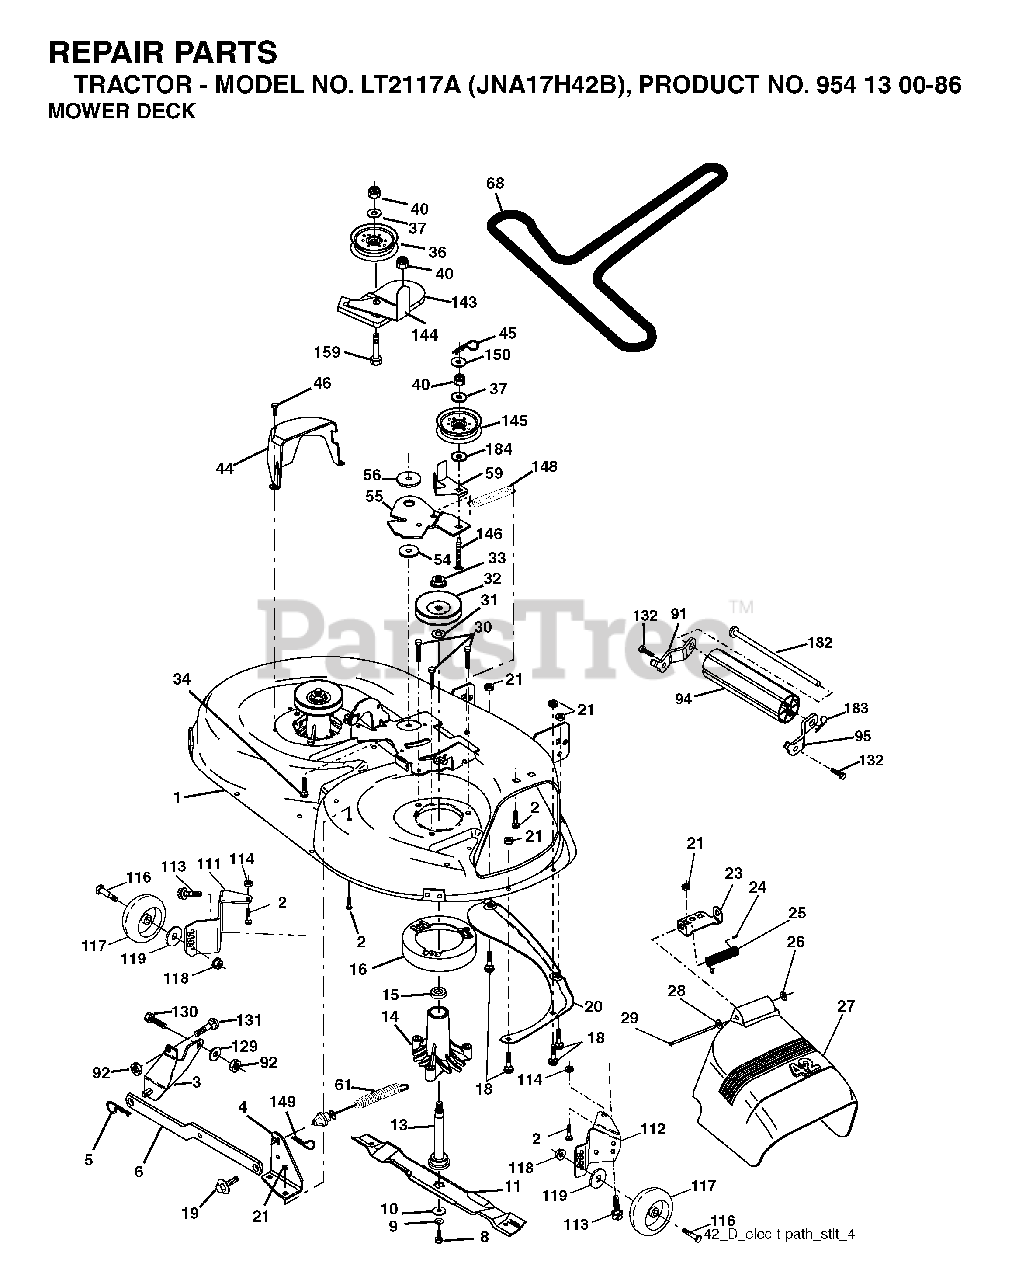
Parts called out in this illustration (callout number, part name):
1	42" DECK KIT
2	BOLT
3	BRKT ASM SWAY BAR
4	BRACKET SWAY BAR 42" DECK
5	RETAINER-SPRNG RB
6	BAR SWAY DECK
8	BLADE BOLT
9	LOCKWASHER
10	WASHER.BLADE
11	BLADE.42".MULCH
13	SHAFT ASM VENT
14	HSG MANDREL
16	STRIPPER, MWR ROUND
18	BOLT
19	BOLT SHD 5/16-18
20	BAFFLE.VORTEX
21	LOCKNUT
23	BRKT, DEFL. MOWER
24	CAP-SLEEVE LT
25	SPRING TORSION
26	NUT PUSH M
27	SHIELD DEFLECTOR
28	WASHER
29	ROD.HINGE
30	SCREW, WASHER HEAD
31	WASHER
32	PULLEY/MANDREL
33	NUT, FLG TOPLOCK 9/16"
34	BOLT
36	FLAT IDLER PULLEY
40	LOCKNUT
44	GUARD MANDREL LH BLACK
45	RETAINER M
46	SCREW.1/4-20X5/8
55	ARM IDLER 42" MOWER LT/YT
56	SPACER.RETAINER.MOWER
59	GUARD, BELT
61	SPRING EXT ELEC CLUTCH
68	V-BELT PRIMARY 42"
91	BRACKET ASM NOSEROLLER LH
92	NUT
94	NOSE ROLLER
95	BRACKET ASM NOSEROLLER RH
111	BRACKET, WHEEL
112	BRACKET, WHEEL
113	SCREW.3/8-16X.625
114	NUT
116	PEDAL COVER T
117	WHEEL.GAUGE.STANDARD
118	LOCKNUT
119	WASHER
129	WASHER
131	BOLT D
132	SCREW, 3/8-16X3/4
143	BRACKET, ARM IDLER
144	KEEPER.BELT.42".CLUTCH.CABLE
145	PULLEY
146	BOLT, CARRIAGE IDLER BLACK
148	IDLER RETURN SPRING
149	SPRING.RETAINER.YELLOW.ZINC
150	WASHER PM
159	BOLT
182	ROD ROLLER NOSE STANDARD
183	SPRING RETAINER
184	WASHER
